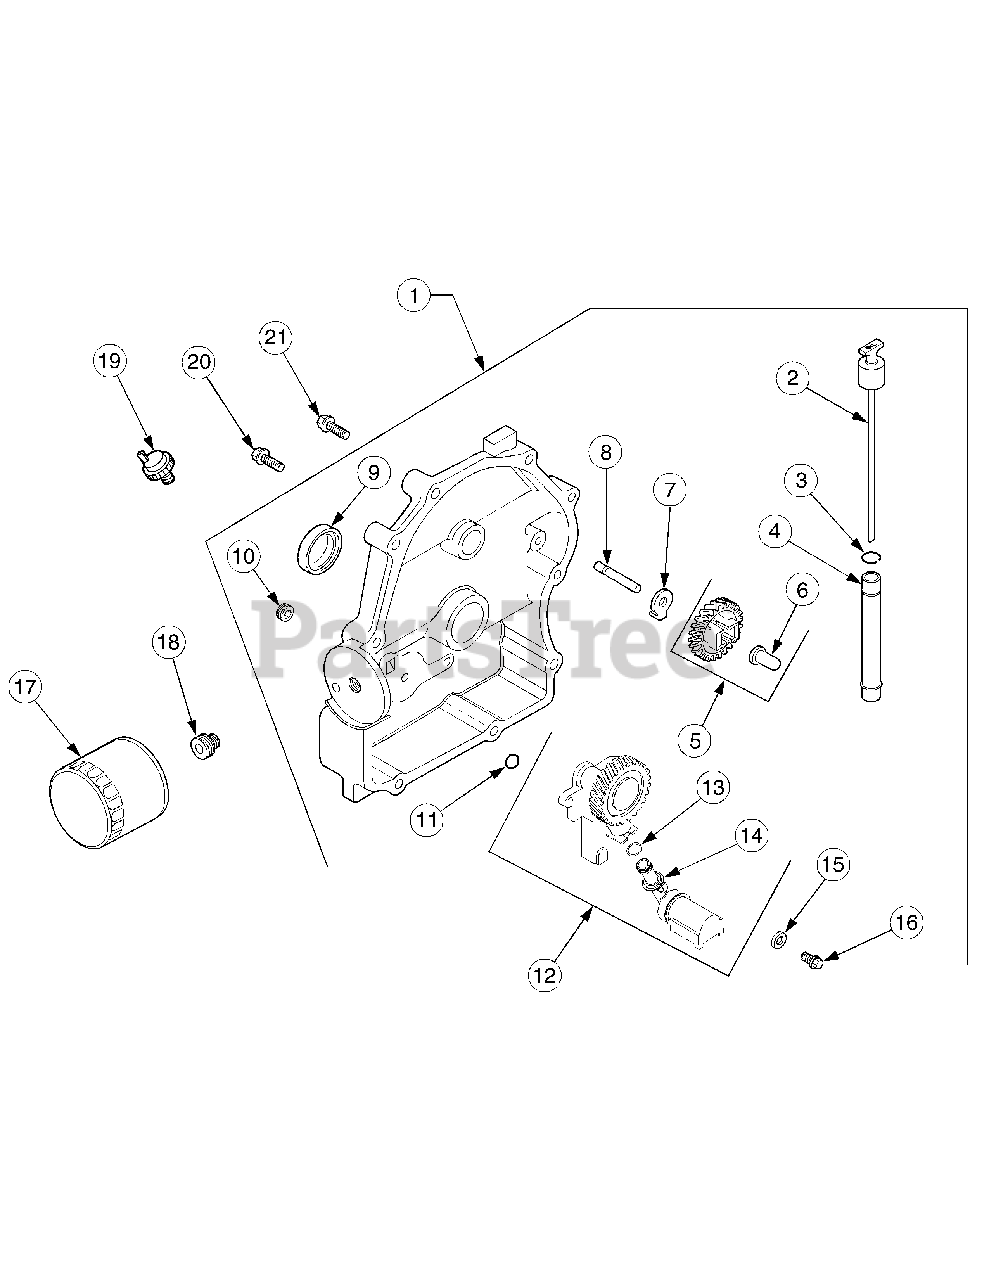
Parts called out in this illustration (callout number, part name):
1	Plate Assy, Closure (Incl. Ref #2-15)
4	Tube, Oil Fill/Dipstick
5	Kit, Governor Gear (Incl. Ref #6)
6	Pin, Governor Regulating
8	Shaft, Governor Gear
9	Seal, Oil (PTO end)
10	Plug, Pipe 1/8
12	Oil Pump Assy (Incl. Ref #13-14)
13	O-Ring, Oil Pick-up
14	Pick-up, Oil
15	Washer, Plain
16	Screw, Hex Flange, M6 x 1.0 x 25
17	Filter, Oil
18	Nipple, Oil Filter
19	Switch, Pressure
20	Screw, Hex Flange, M8 x 1.25 x 45
21	Screw, Hex Flange, M8 x 1.25 x 45
